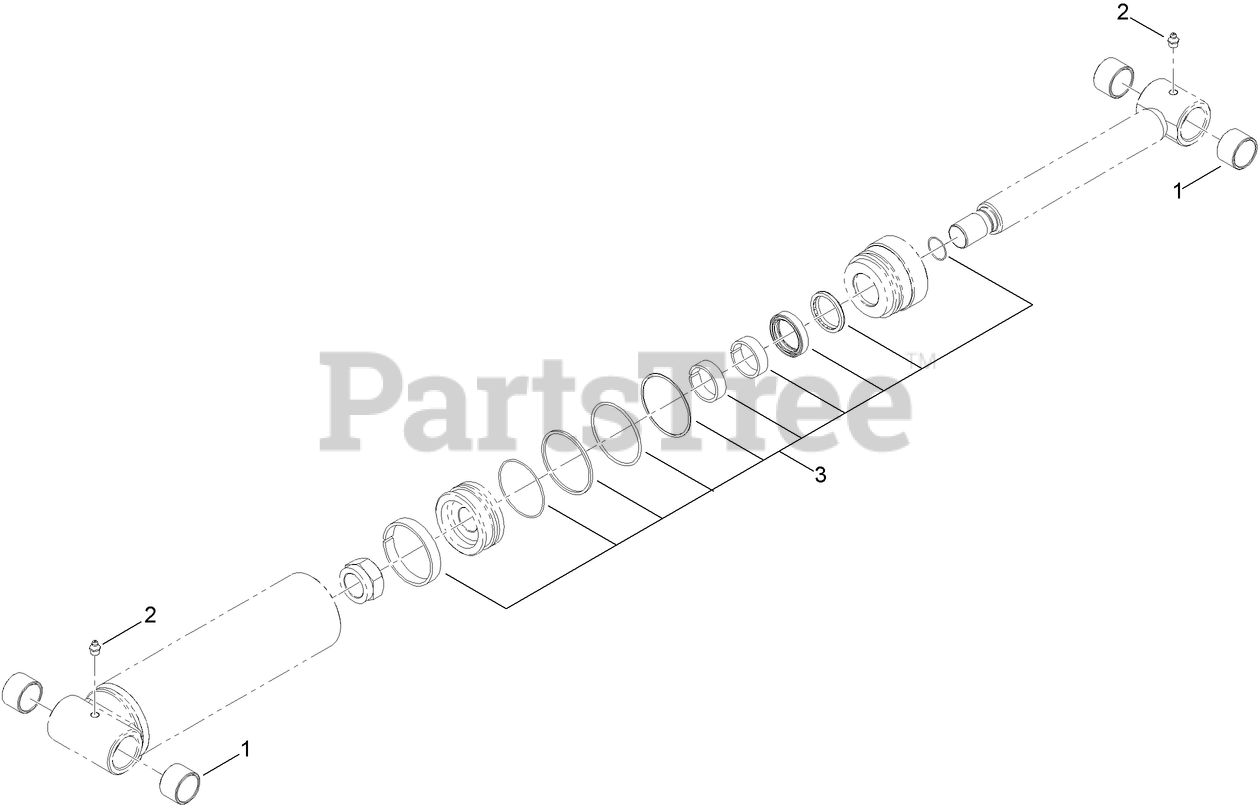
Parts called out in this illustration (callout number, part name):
1	BUSHING-ROD END, CYLINDER
2	FITTING-GREASE
3	SEAL KIT
